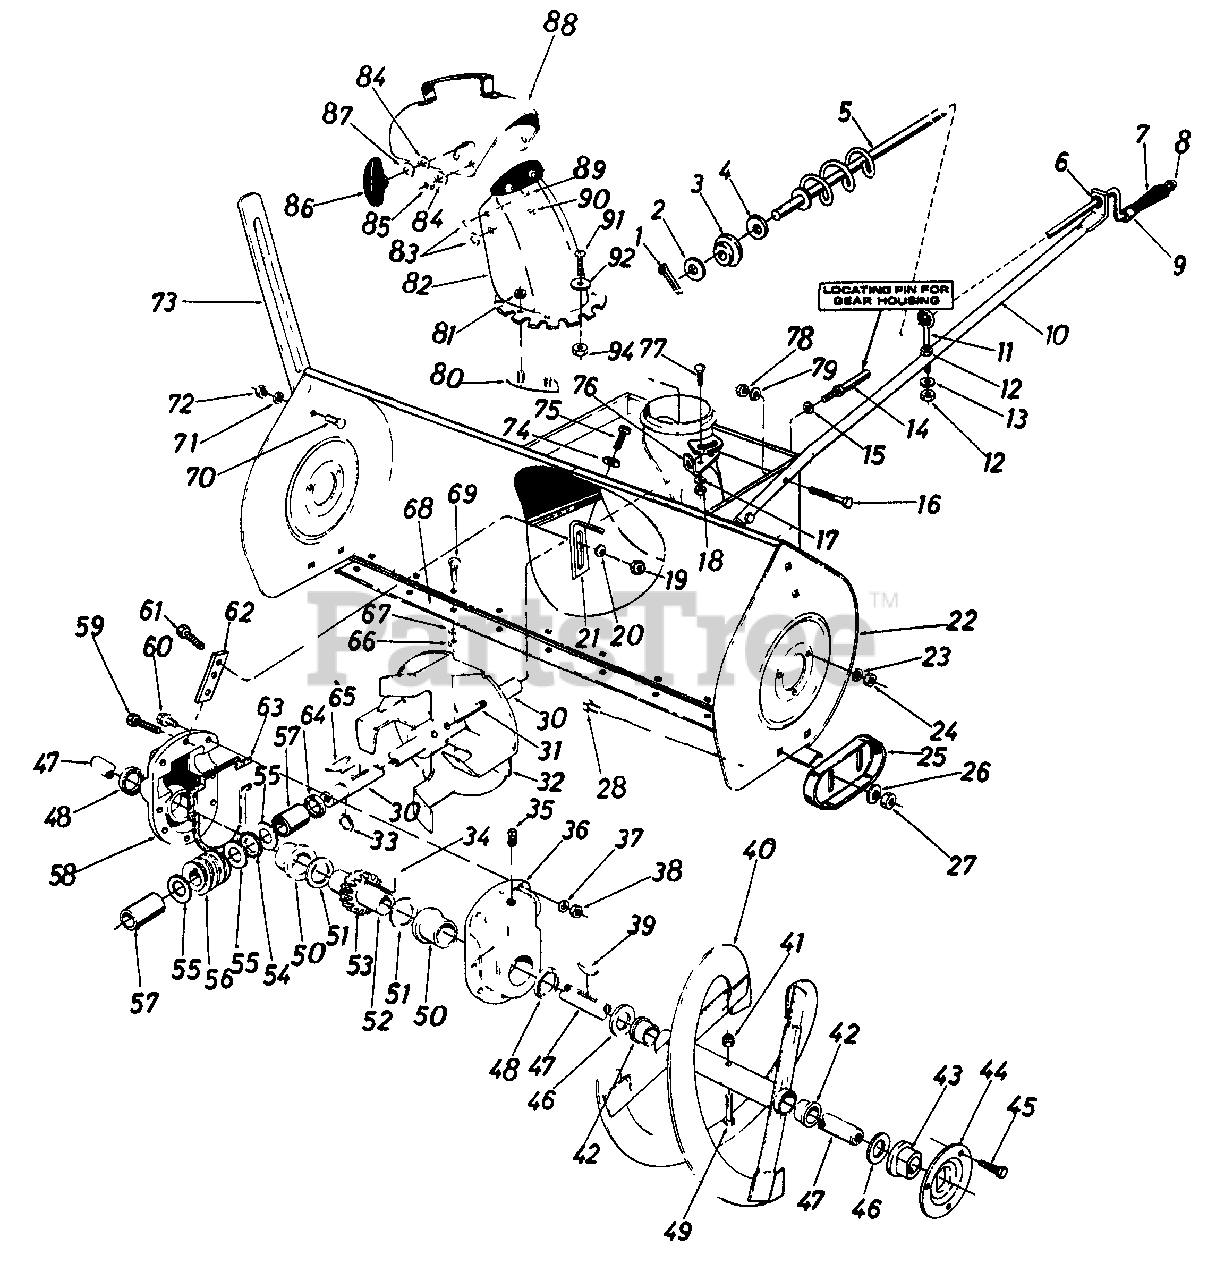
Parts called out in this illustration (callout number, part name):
2	Fl.-Wash. .39" I.D. x .62" O.D.
3	Plastic Bushing
4	Fl.-Wash. .385" I.D. x .62" O.D.
5	Chute Crank Ass'y.
6	Plastic Bushing
7	Knob Ball 3/8 Dia. Hole
8	Push Nut 3/8" Rod
9	Spacer .385 I.D. x .50" I.D.
10	Chute Crank Support Tubing
12	Hex Nut 5/16-18 Thd.*
13	Bell.-Wash. .345" I.D. x .88" O.D.
14	Stud 3i8-16 x 2.75" Lg.
15	Bell.-Wash. .400" I.D. x .88" O.D.
16	Hex Bolt 3/8-24 x 1.25" Lg.*
17	Bell.-Wash. .345" I.D. x .88" O.D.
18	Hex Nut 5/16-18 Thd.*
19	Hex Nut 1/4-28 Thd.
20	Bell.-Wash. .265" I.D. x .75" O.D.
22	45" Snow Blower Housing Ass'y
23	L.-Wash. 5/16" I.D.*
24	Hex Nut 5/16-18 Thd.*
25	Slide Shoe
26	Bell.-Wash . .400" I.D. x .88" O.D.
27	Hex Jam Nut 3/8-16 Thd.
28	Carriage Bolt 3/8-16 x .62" Lg.*
30	Blower Axle .875" Dia. x 14.75" Lg.
31	Spring Pin Spir. 5/16" Dia. x 1.75" Lg.
34	#91 Woodr-Key 1/4 x 3/4" Dia. (HDN)
36	Comp. Gear Hsg. Half-L.H.
37	Spr.-Wash. .32" I.D. x .62" O.D
38	Hex Ins. L.-Nut 5/16-18 Thd.
39	#91 Woodr-Key 1/4 x 3/4" Dia. (HDN)
41	Hex Ins. L.-Nut 5/16-18 Thd.
42	Plastic Bushing
43	Flange Brg. w/ flats 1" I.D.
44	Bearing Housing
45	Hex Sems Bolt 5/16-18 x .75" Lg. *
46	FI .-Wash . 1.00" I.D. x 1.75" O.D.
48	Flange Bearing 1.503" I.D.
49	Shear Bolt 5/16-18 x 1.75" Lg.
50	Oil Seal 1.50" I.D.
51	Fl.-Wash.1.50" I.D. x 2.00" O.D.
52	Worm Gear Shaft
53	Double Threaded Worm Gear-L.H.
54	Thrust Brg.-.88" I.D. x 1.44" O.D.
55	Fl.-Wash..88" I.D. x1.4" O.D.
56	Double Threaded Worm-L.H.
57	Sleeve
58	Complete Gear Hsg. Half-R.H.
59	Hex Bolt5/16-18x1.25" Lg.*
60	Hex Bolt 5/16-18 x 1.0" Lg. (Grade 5)
61	Hex Bolt 1/4-28 x .75" Lg.
62	Gear Housing Support Plate
63	Rubber Gasket
64	Oil Seal-.875" I.D.
65	#9 Hi-Pro Key 3/16 x 3/4" Dia. (HT.)
66	Hex Nut 5/16-18 Thd.*
67	L.-Wash.5/16" I.D.*
69	Carriage Bolt 5/16-18 x 1.00" Lg.
70	Carriage Bolt 5/16-18 x .62" Lg.*
71	L.-Wash. 5/16" I.D.*
72	Hex Nut 5/16-18 Thd.*
73	Guide Blade
74	Bell.-Wash. .345" I.D. x .88" O.D.
75	Hex Wash. Hd. AB Tap Scr 5/16 x .75" Lg.
77	Carriage Bolt 5/16-18 x .75" Lg.*
78	Hex Ins. L.-Nut 3/8-24 Thd.
79	L.-Wash. 3/8" I.D.*
80	Chute F lange Keeper
81	Hex Cent. L.-Nut 1/4-20 Thd.
82	Chute Ass'y. w/ Chute Guard
83	Fl.-Wash. .285" I.D. x 1.25" O.D.
84	Bell.-Wash. .345" I.D. x .88" O.D.
85	Hex Cent. L.-Nut 5/16-18 Thd.
86	Knob Handle
87	Bell.-Wash. .345" I.D. x .88" O.D.
88	Top Chute Ass'y.
89	Carriage Bolt 5/16-18 x 1.00" Lg.*
90	Carriage Bolt 5/16-18 x .62" Lg *
91	Truss Mach. Scr. 1/4-20 x .50"
92	Fl.-Vl.ash. .285" I.D. x 1.25" O.D.
94	Hex Cent. L-Nut-1/4-20 Thd.
